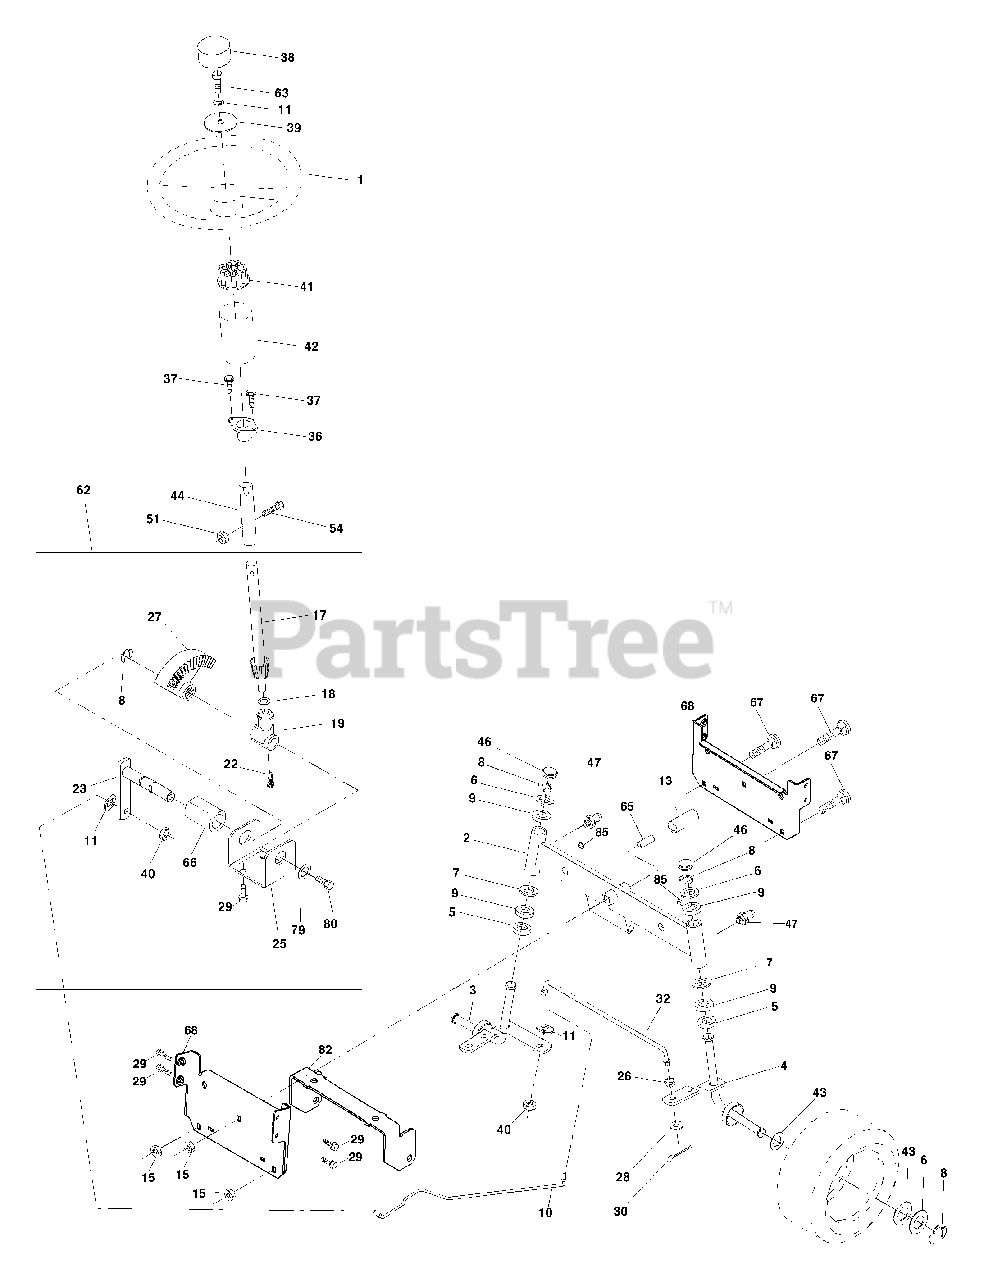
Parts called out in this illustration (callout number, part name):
1	Wheel Steering
2	Axle Asm STMP Dropped STL
3	Spindle Asm LH
4	Spindle Asm RH
5	Bearing Race Thrust Harden
6	Washer 25/32 X 1-5/8 X 16 Ga
7	Washer 27/32 X 1-1/4 X 16 Ga
8	Ring Klip #t5304-75
9	Bearing Col Strg Blk
11	Washer Lock Hvy Hlcl Spr 3/8
13	Spacer Brg Axle Front
15	Nut Hexflange Lock
17	Shaft Asm Strg
18	Washer Thrust 515x 750x 033
19	Support Shaft
22	Screw Hex Wsh Hd Torx
23	Shaft Asm Pittman
25	Bracket Steering
26	Bushing Link Drag Blk LR
27	Gear Sector
28	Washer 13/32 X 7/8 X 16 Ga
29	Screw 3/8-16x3/4
30	Pin Cotter 1/8 X 3/4 Cad
32	Rod Tie Wire Form 19 75 Mech
36	Bushing Strg
38	Insert Cap Strg Wh
39	Washer 13/32 X 1-1/20 x 11 Ga
40	Lock nut 3/8-24
41	Adaptor Wheel Strg
42	Boot Steering Shaft
43	Washer 25/32 X 1 1/4 X 16 Ga
44	Extension Steering Shaft LR/LT
46	Cap Spindle Fr Top Blk
47	Fitting Grease
51	Nut Lock Hex w/Ins 5/16-18
54	Bolt Fin Hex 5/16-18 Unc x 1-1/4
62	Kit, Steering Assembly Svc
63	Bolt Fin Hex 3/8-16unc x 1 Gr. 5
65	Spacer Brace Axle
66	Bearing Arm Pittman
67	Bolt Rdhd Sqnk 3/8-16 x 2-1/4
68	Axle, Brace
79	Washer 13/32 x 1-1/4 x 12 Ga
80	Bolt Hex Nylon 3/8-16 x 3/4
82	Bracket Susp Chassis Front
85	Fastner Christmas Tree
